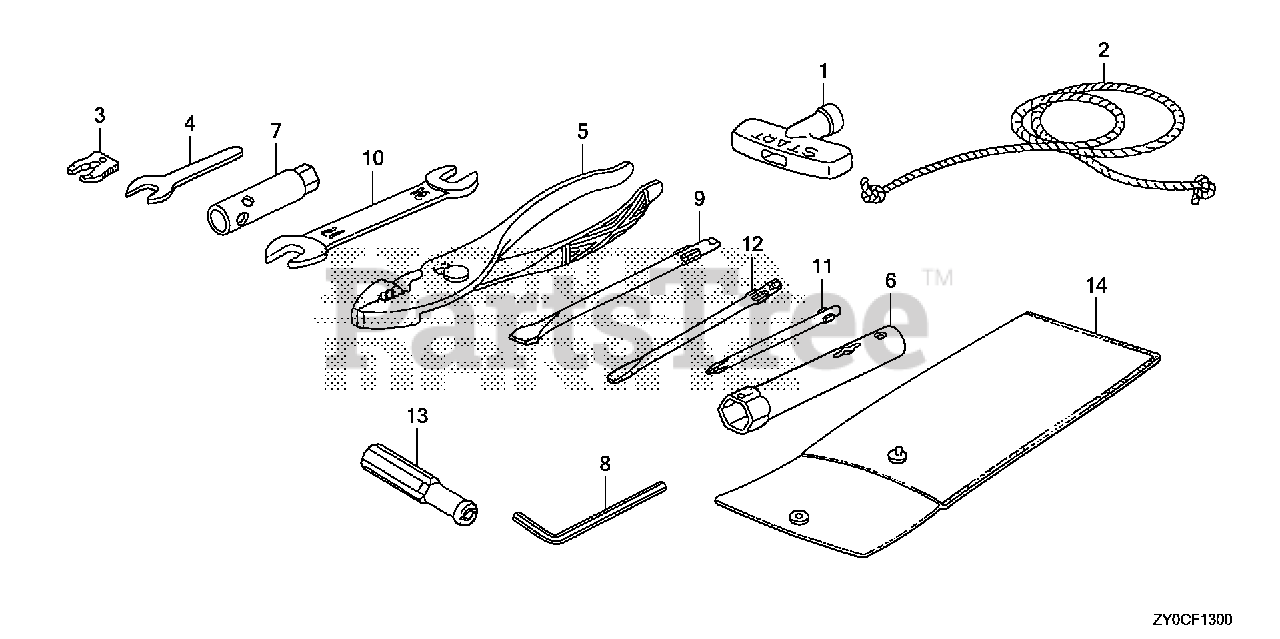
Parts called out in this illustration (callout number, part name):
1	KNOB, RECOIL SRARTER
2	ROPE, RECOIL STARTER (1300MM)
5	PLIERS (135) (RIKEN)
6	WRENCH, SPARK PLUG
7	WRENCH, BOX (10MM)
8	WRENCH, HEX. (4MM)
9	SCREWDRIVER, CHECK BOLT
10	SPANNER (10X12)
11	DRIVER 1, PLUS SCREW (NO.2)
12	DRIVER 3, MINUS SCREW (NO.2)
13	GRIP, SCREW DRIVER
14	BAG, TOOL (160MM)
